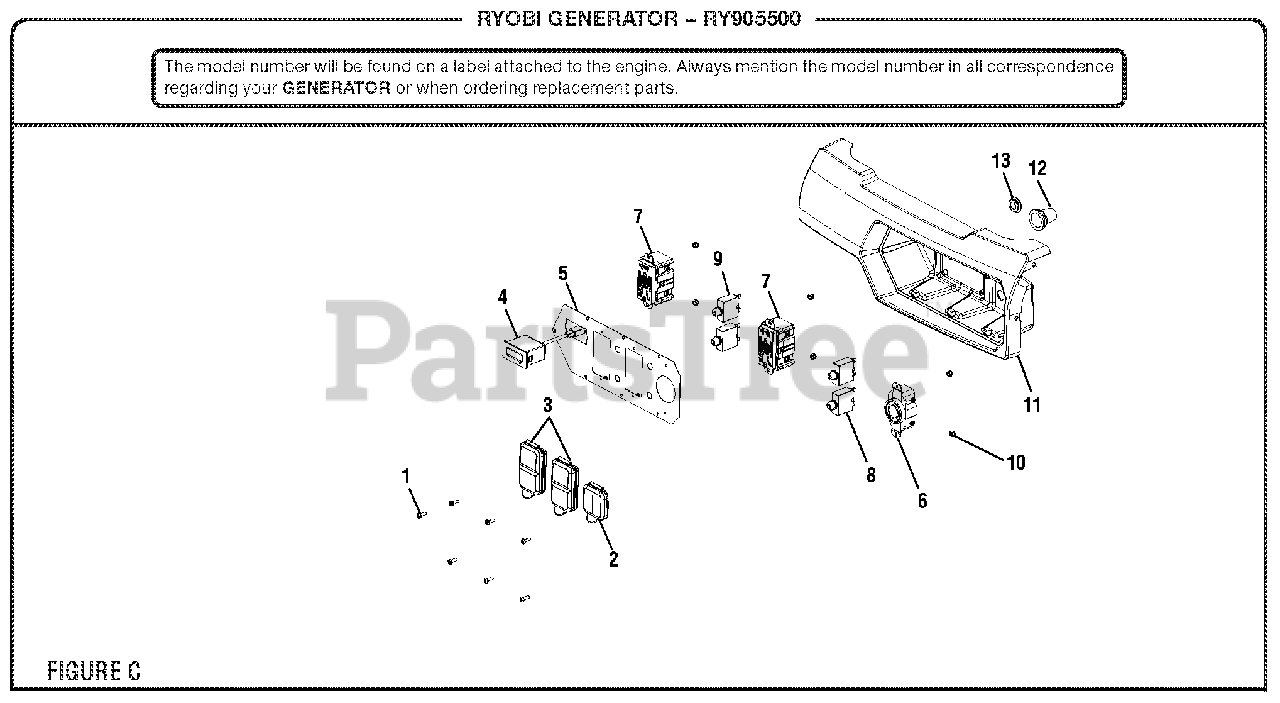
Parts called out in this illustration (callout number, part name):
1	Screw (M8-18 x 1/2 in., T20 Torx Hd.)
2	Outlet Cover
3	Duplex Outlet Cover
4	Digital Meter
5	Front Panel
6	Twist Lock Recepticle (120/240 Volt, 30 Amp, L14-30)
7	Duplex Receptacle (120V)
8	Circuit Breaker (25 Amp)
9	Circuit Breaker (20 Amp)
10	Lock Nut (#6-32)
11	Control Box (Back Panel)
12	Rubber Boot
